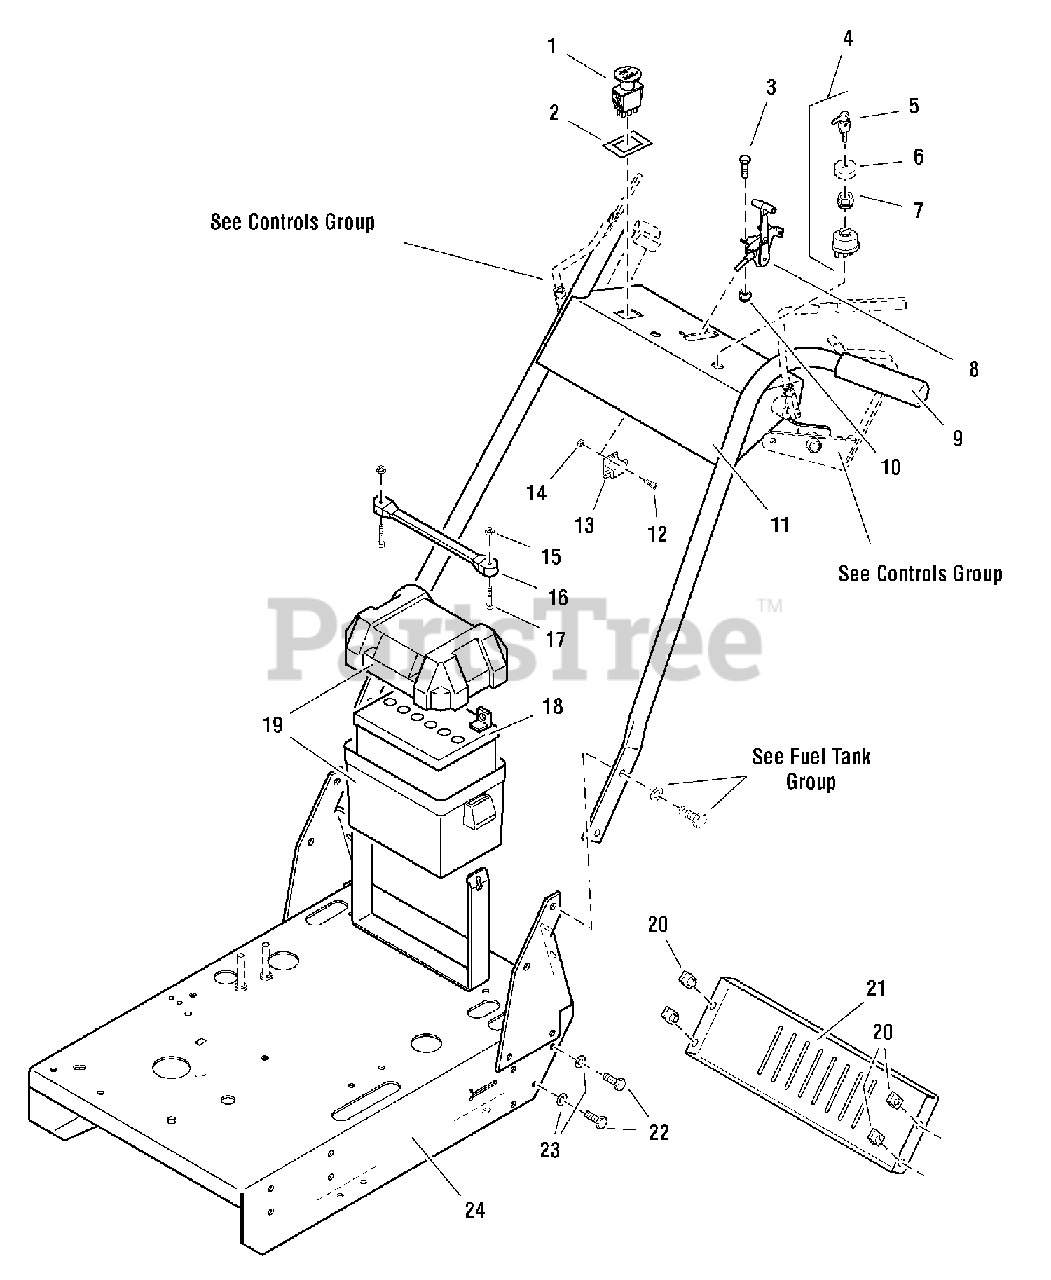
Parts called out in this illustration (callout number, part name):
1	SWITCH, PTO
2	SWITCH RETAINER RING
3	CAPSCREW, Hex Head, 1/4-20 x 3/4
4	SWITCH, Ignition, Complete (includes Ref 5 - 7)
5	KEY, Ignition, Molded (set of 2)
7	PLASTIC NUT
8	CABLE, Throttle Control
9	FOAM GRIP
10	NUT, Hex Nylon Lock, 1/4-20
11	HANDLE BAR ASSEMBLY
12	SCREW, Phillips Head, #10-24 x 1/2
14	NUT, Hex, #10-24
15	NUT, Hex Nylon Lock, #10-24
16	RUBBER STRAP
17	SCREW, Phillips Head, #10-24 x 1
18	BATTERY, 12Volt (340 CCA)
19	BATTERY BOX
20	BODY CLIP, 5/16-18
21	REAR SHIELD
22	CAPSCREW, Hex Head, 5/16-18 x 3/4
23	WASHER, 5/16
24	ENGINE DECK ASSEMBLY
